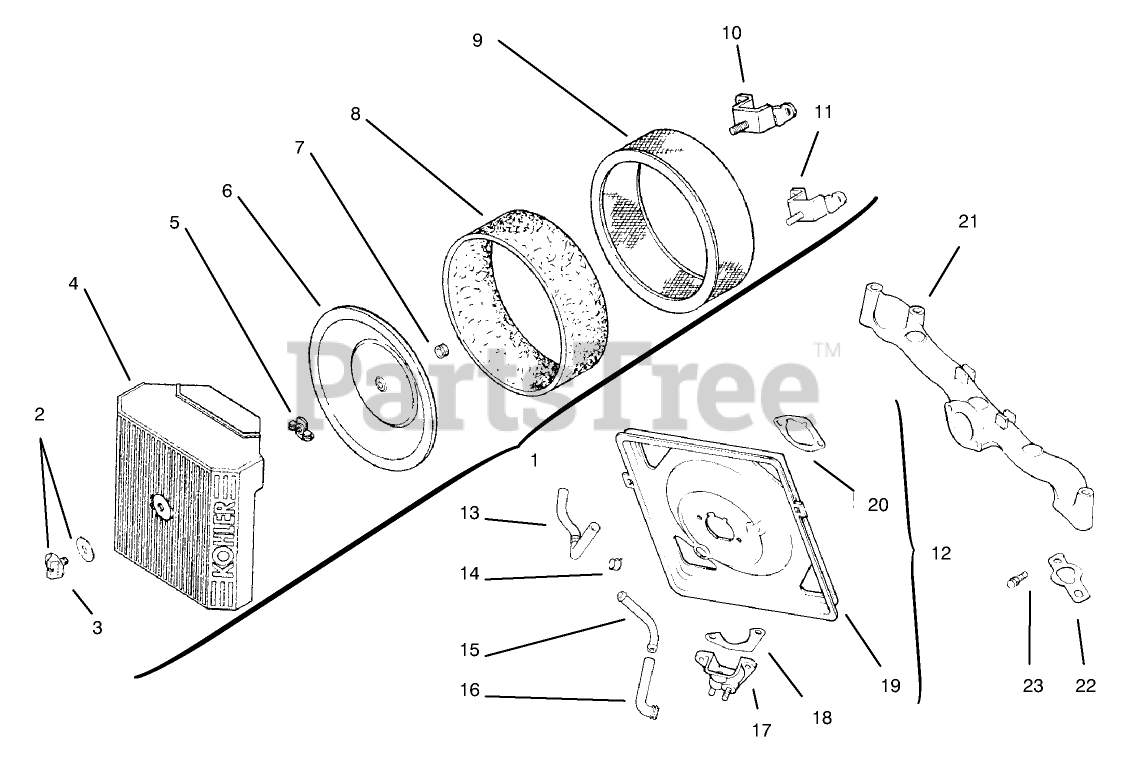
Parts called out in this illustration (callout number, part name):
1	Kit-A/C Cover INCL 2-4 (Only On: 72103;
2	Spring-Latch (Only On: 72103)
3	Latch-Lever (Only On: 72103)
4	Pin-Latch Lever (Only On: 72103)
5	Nut-Wing
6	Seal-Air Intake (Only On: 72103)
7	Cover-Inner Air Cleaner
8	Element-Precleaner
9	Element-Air Cleaner
10	Cup-Fuel Spitback (Only On: 72103)
11	Gasket-Fuel Spitback Cup (Only On: 72103, 72083)
12	Base-Air Cleaner (Only On: 72103)
13	Gasket-A/C Base (Only On: 72103, 72083)
14	Manifold-Intake (Only On: 72103)
15	Gasket-Intake Manifold
